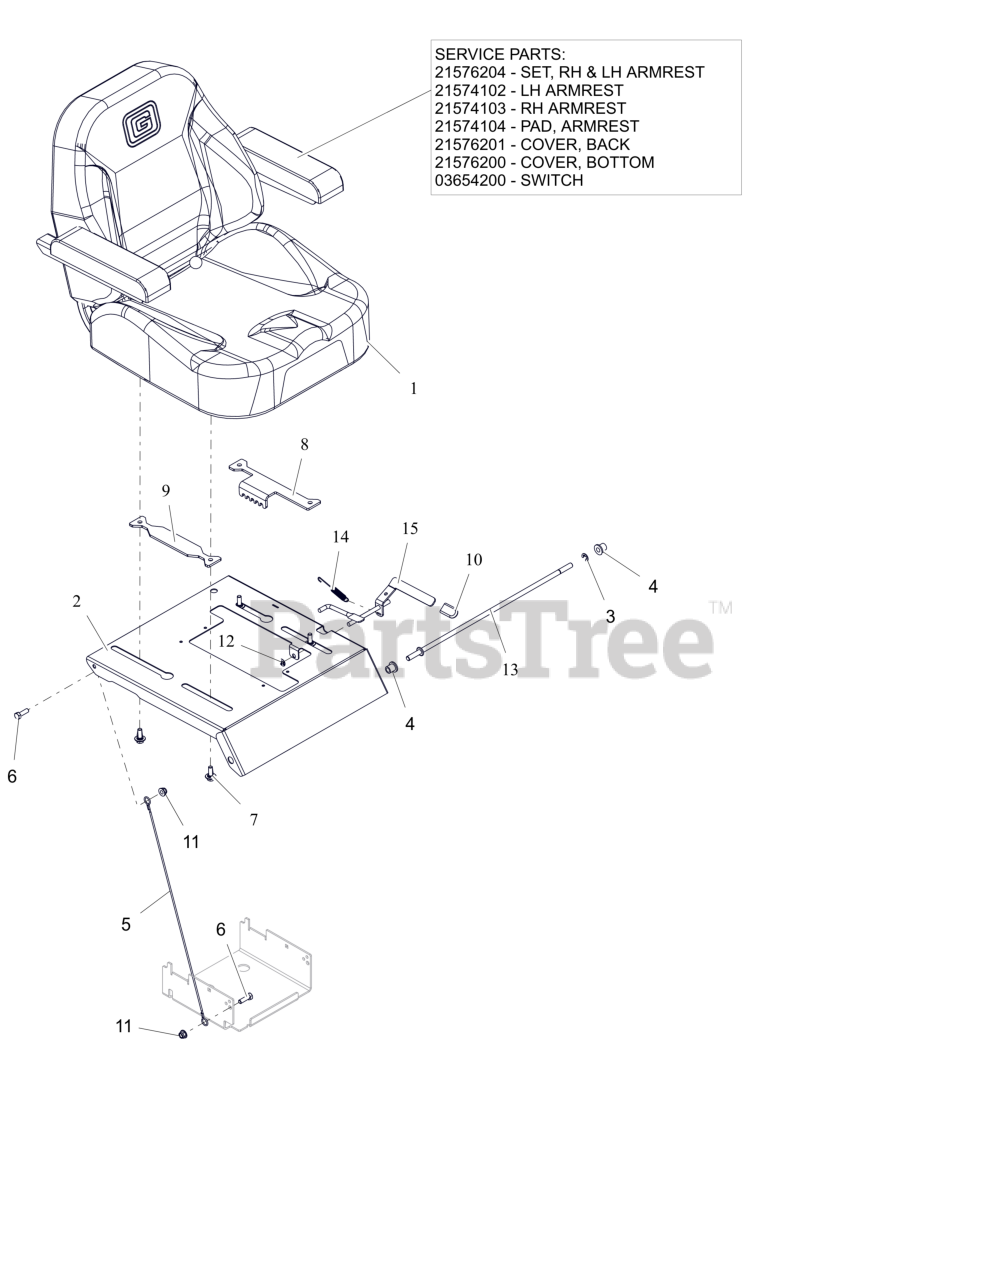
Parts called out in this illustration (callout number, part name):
1	SEAT- ZTX
1	KIT- PADDED ARM RESTS LH&RH
1	KIT, ARM REST LH
1	KIT, ARM REST RH
1	KIT, ARM REST PAD
1	BACK COVER
1	BOTTOM COVER
1	SWITCH- SEAT
2	PLATE- SEAT-ZTX 2022
3	RG-RTNG-EXT .375X.035 TYP E
4	BSHG-FLG .38X.580X.667X.750
5	LANYARD, SEAT CABLE .093X19.5
6	BLT,HEX .31-18X1.00 G5 ZCC
7	BLT, SHLDR .31-18 X .100
8	PKG-SEAT PAD-HD
9	PLATE, ADJUSTABLE SEAT TRACK (BLACK)
10	GRIP, SEAT LEVER, GREY
11	NUT,NYL-FLG .31-18 GF ZCC
12	NUT-PUSH .312
13	ROD- SEAT PIVOT
14	SG-TENS .043X.44X3.31 WLD 5.8
15	WLDMT, ADJUSTABLE SEAT LATCH
